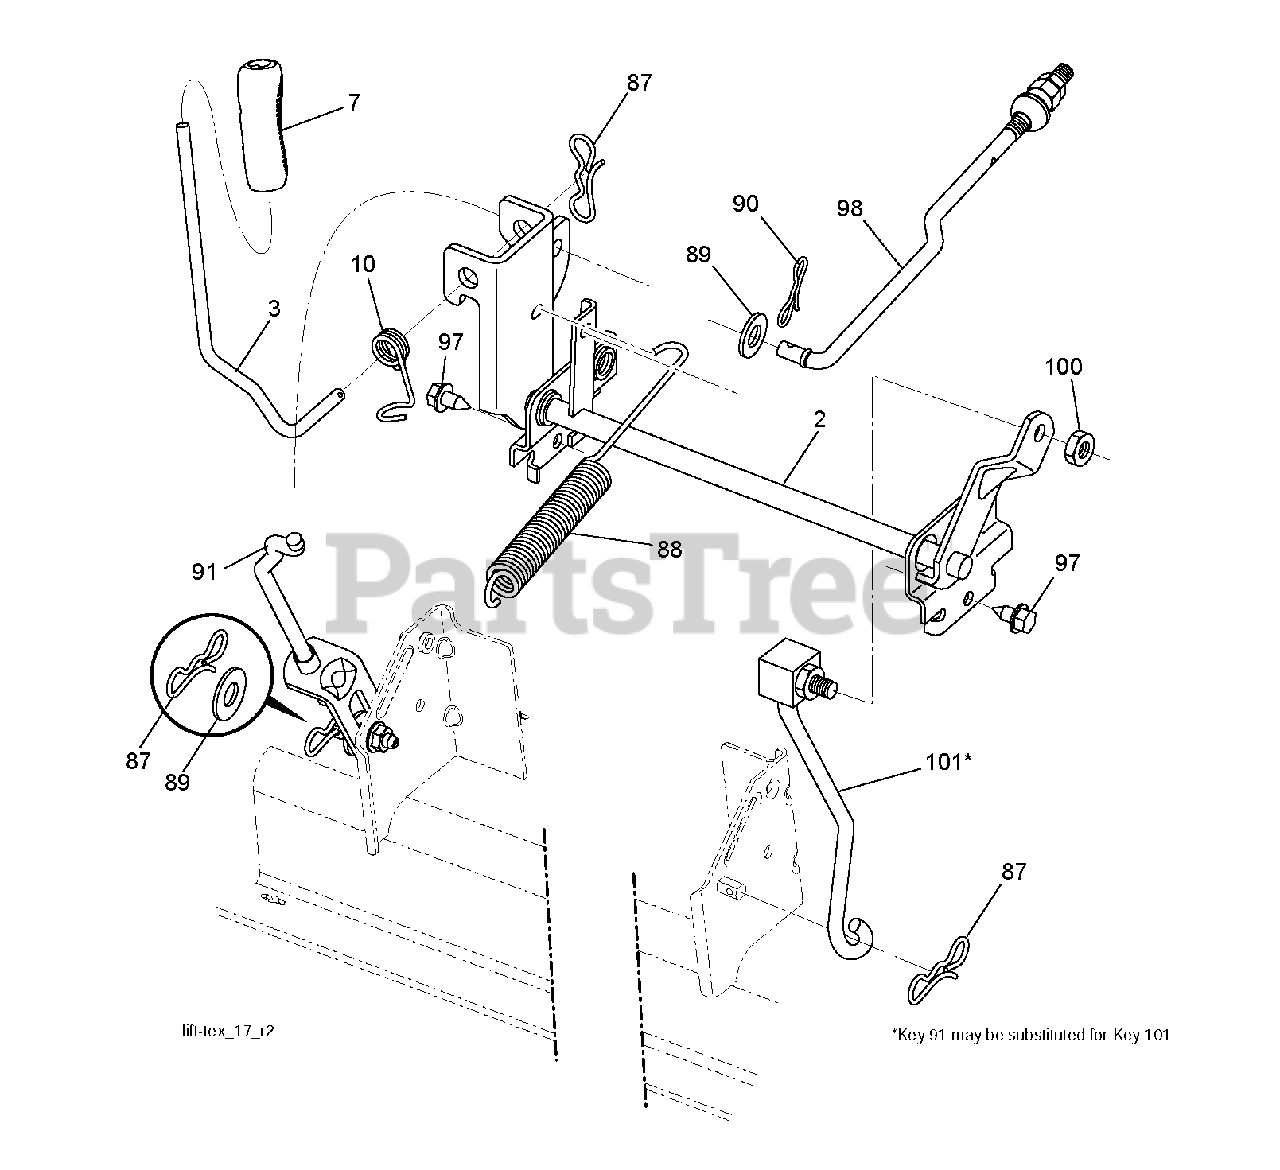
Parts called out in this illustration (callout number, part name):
2	SHAFT.ASM.LIFT.CROSS.H
3	LEVER.LIFT.HANDLE.LT
7	GRIP.HANDLE.LIFT.PVC.BLACK
10	SPRING.TORSION.LIFT.HANDLE
87	PIN.COTTER.7/16.BOW TI
88	SPRING.LIFT.ASSIST
89	WASHER.CLEAR.ZINC
90	PIN.COTTER.5/16.BOW TI
91	LINK.ASM.LIFT.REAR
97	SCREW, 3/8-16X3/4
98	LINK.ASM.SUSP.FRONT.MWR.10.5
100	LOCKNUT
101	LINK.ASM.LIFT.FIXE.38/42/46"
